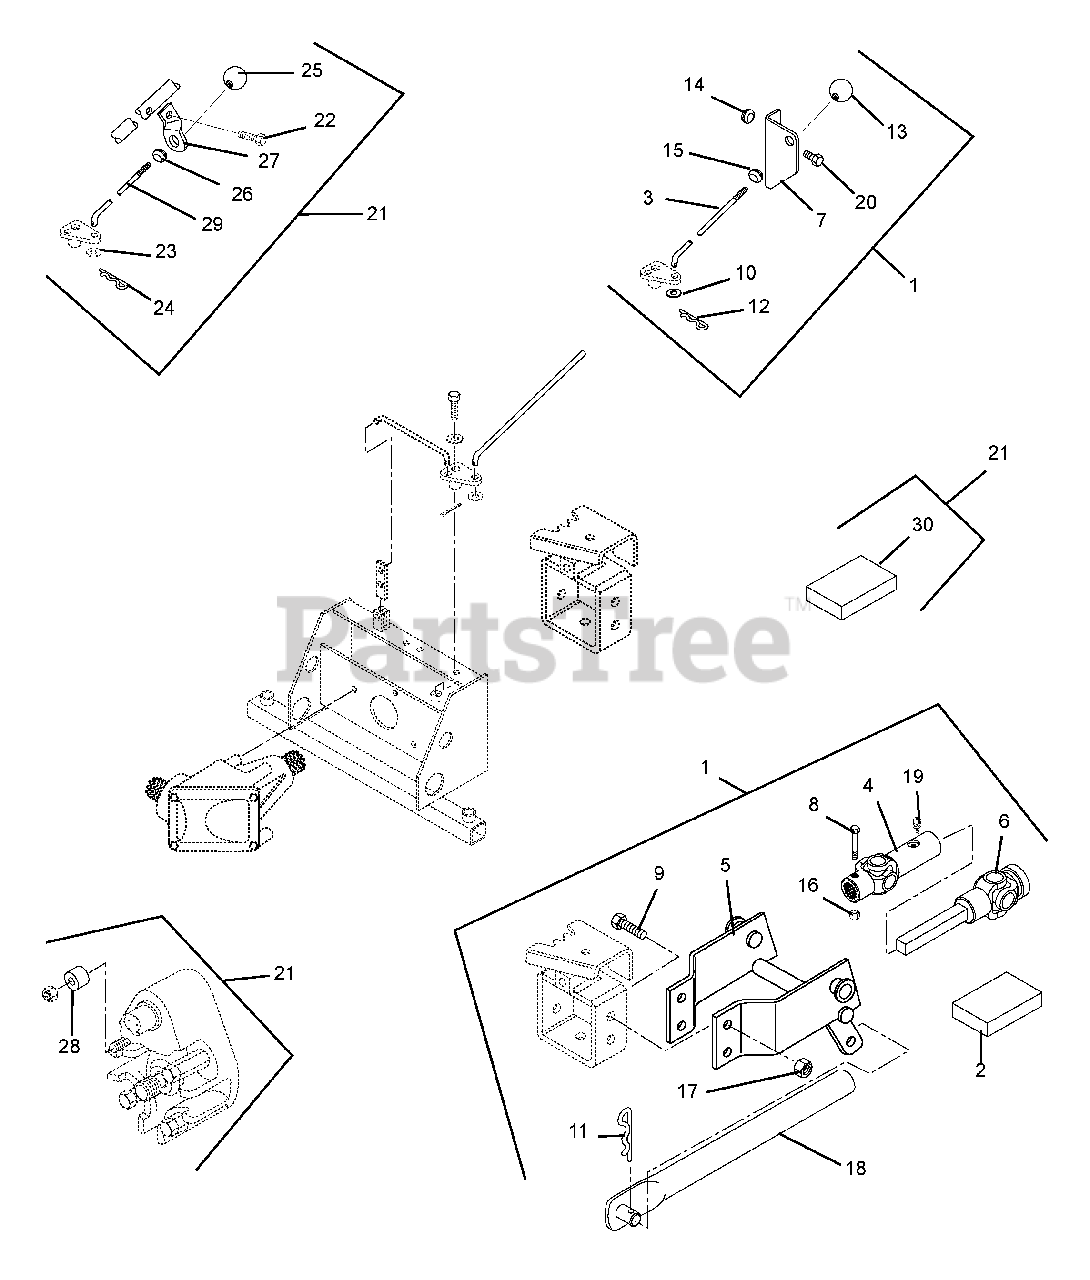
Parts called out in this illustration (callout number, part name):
1	Kit, Power Brush for 4-Wheel Tractor
2	Kit, Universal Joint Repair
3	Rod, Control
4	Universal Joint-Female End
5	Weldment, Adapter
6	Universal Joint-Male
7	Bracket
8	Bolt-Hex .25-20 x 2.00 Grade 5
9	Bolt-Hex .50-13 x 1.50 Grade 5
10	Washer-Flat-Steel .281 x .62 x 065
11	Pin-Hair-External .15 x .937
12	Hair Pin Cotter .08 x .18 x 1.18
13	Knob
14	Grommet, Plastic
15	Grommet, Shifter
16	Nut-Locking-Nylon .25-20
17	Nut-Locking-Nylon .50-13
18	Rod, Push Weldment
19	Fitting-Lube .25-28
20	Screw-Self Tapping .25-20 x .75 Hex Washer Head
21	Kit, Power Brush for 2-Wheel Tractor
22	Bolt-Hex .50-13 x 2.75 Grade 5
23	Washer-Flat-Steel .281 x .62 x .065
24	Hair Pin Cotter .08 x .18 x 1.18
25	Knob
26	Grommet, Shifter
27	Guide, Control Rod
28	Bushing Sleeve .531 x .991 x .600
29	Arm, Control
30	Journal Cross and Bearing Assembly
